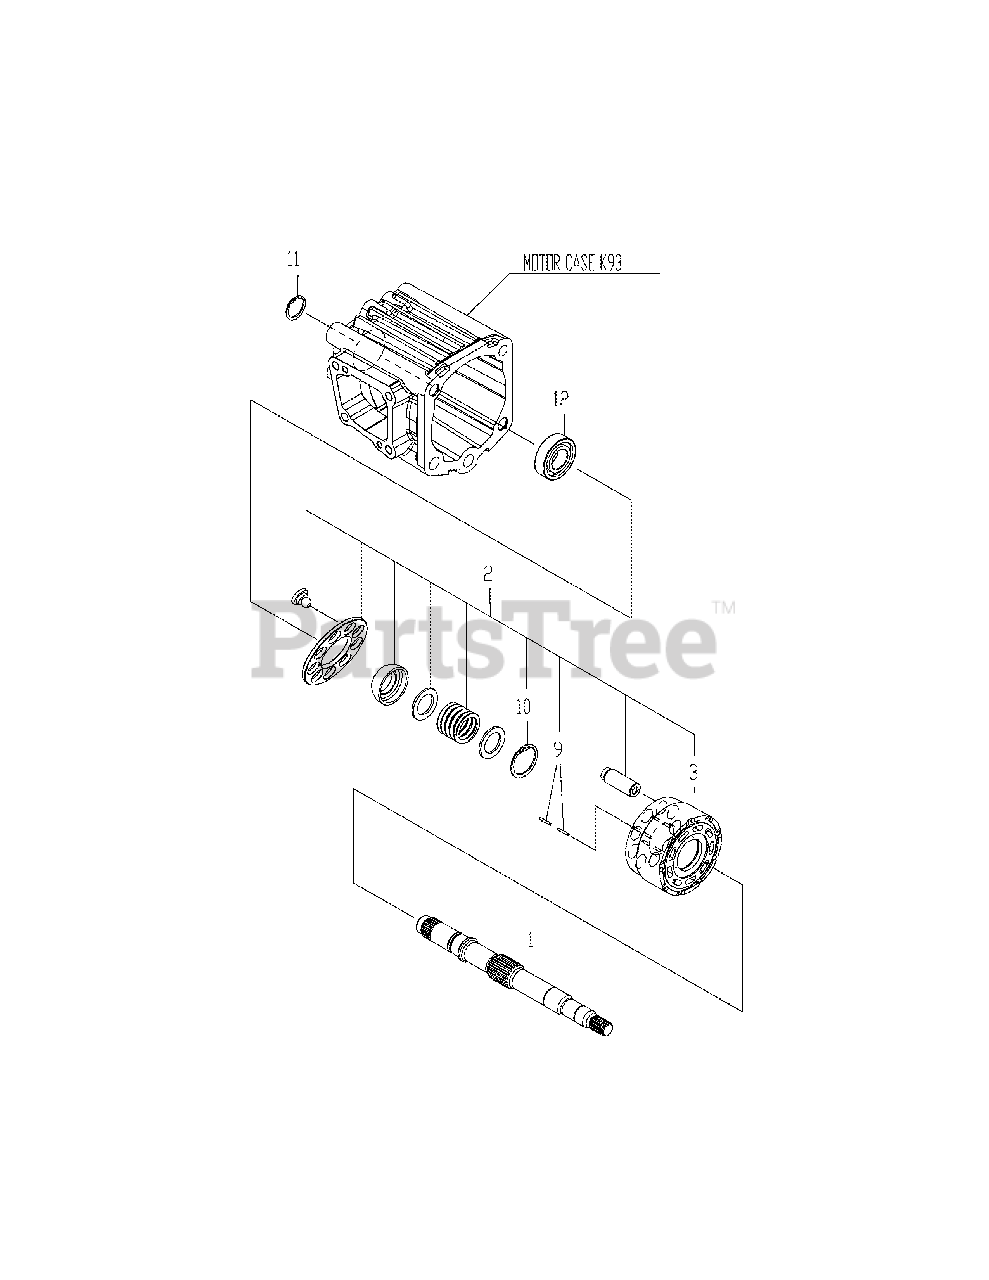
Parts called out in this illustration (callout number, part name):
1	Motor Shaft (K93
2	Block Assy, Cyl
3	Block, Cylinder
12	Bearing, 6004U
